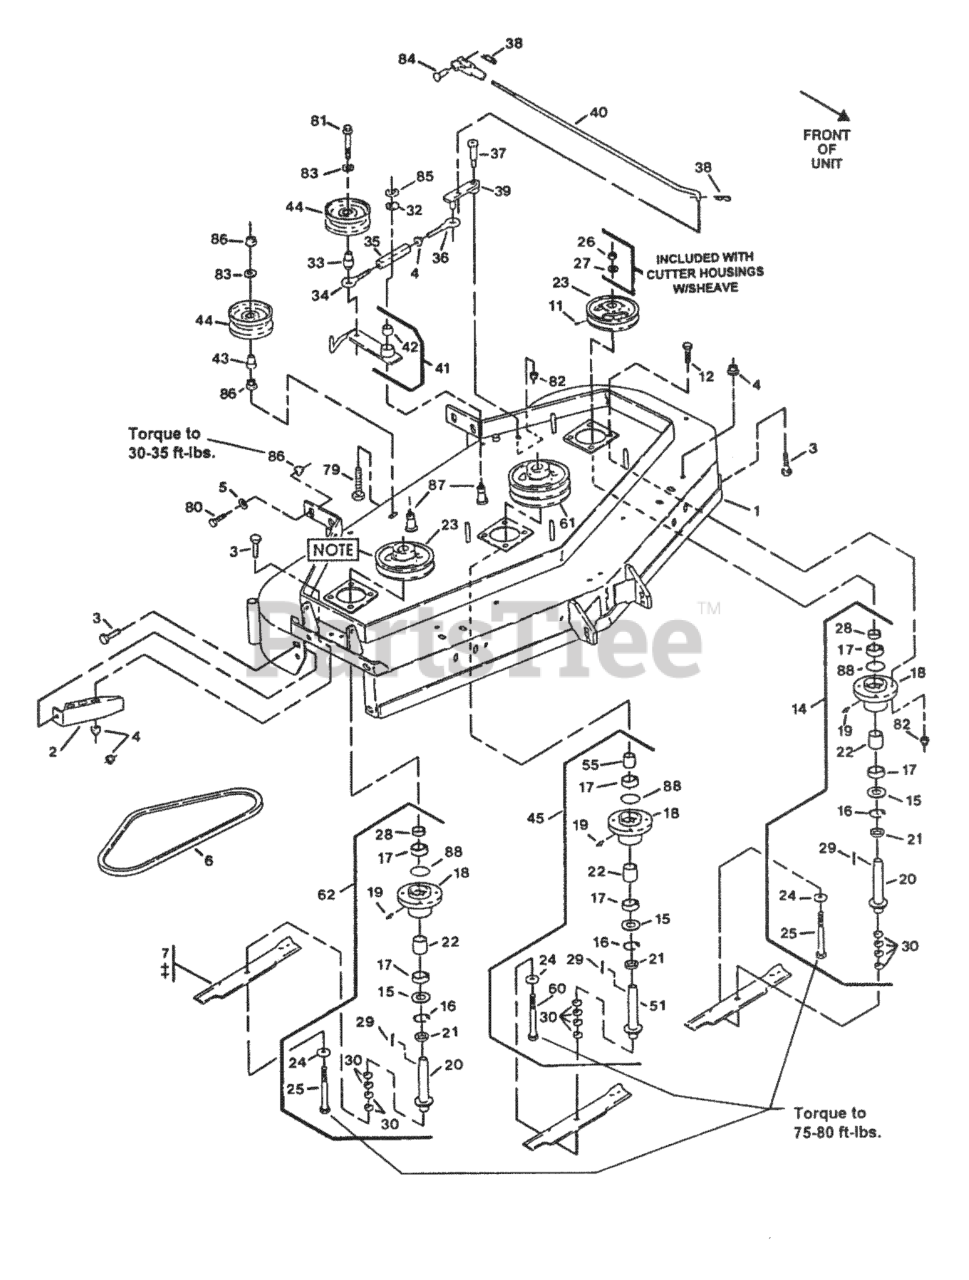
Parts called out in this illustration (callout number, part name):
2	WLD, DISCHARGE BAFFLE
11	SCREW-SET
14	ASM,HOUSING CUTTER
15	SEAL,DUST
16	RING,SNAP WLDS N5000-244
17	BEARING,HD SPINDLE
18	HOUSING,CUTTER
21	SPACER,BEARING &SPINDLE
22	SPACER,BRG/BRG
24	WASHER-SPRING
25	SCREW-CAP, HH
27	WASHER-RETAINER, SHEAVE
31	YOKE-ADJUSTABLE
32	WASHER-SPINDLE
33	BUSHING-ENGAGEMENT
34	EYEBOLT-THREAD, LH
35	BODY-TURNBUCKLE
36	EYEBOLT-THREAD, RH
37	BOLT,SHLDR KSKH
38	PIN-COTTER
42	BEARING,POWDERED METAL
55	SPACER,BEARING/SHEAVE
60	SCRW,CAP HH 5/8-18X8.5
75	WASHER-RETAINER, SHEAVE
79	BOLT,TAP HH3/8-16X2-1/4
84	PIN-CLEVIS
